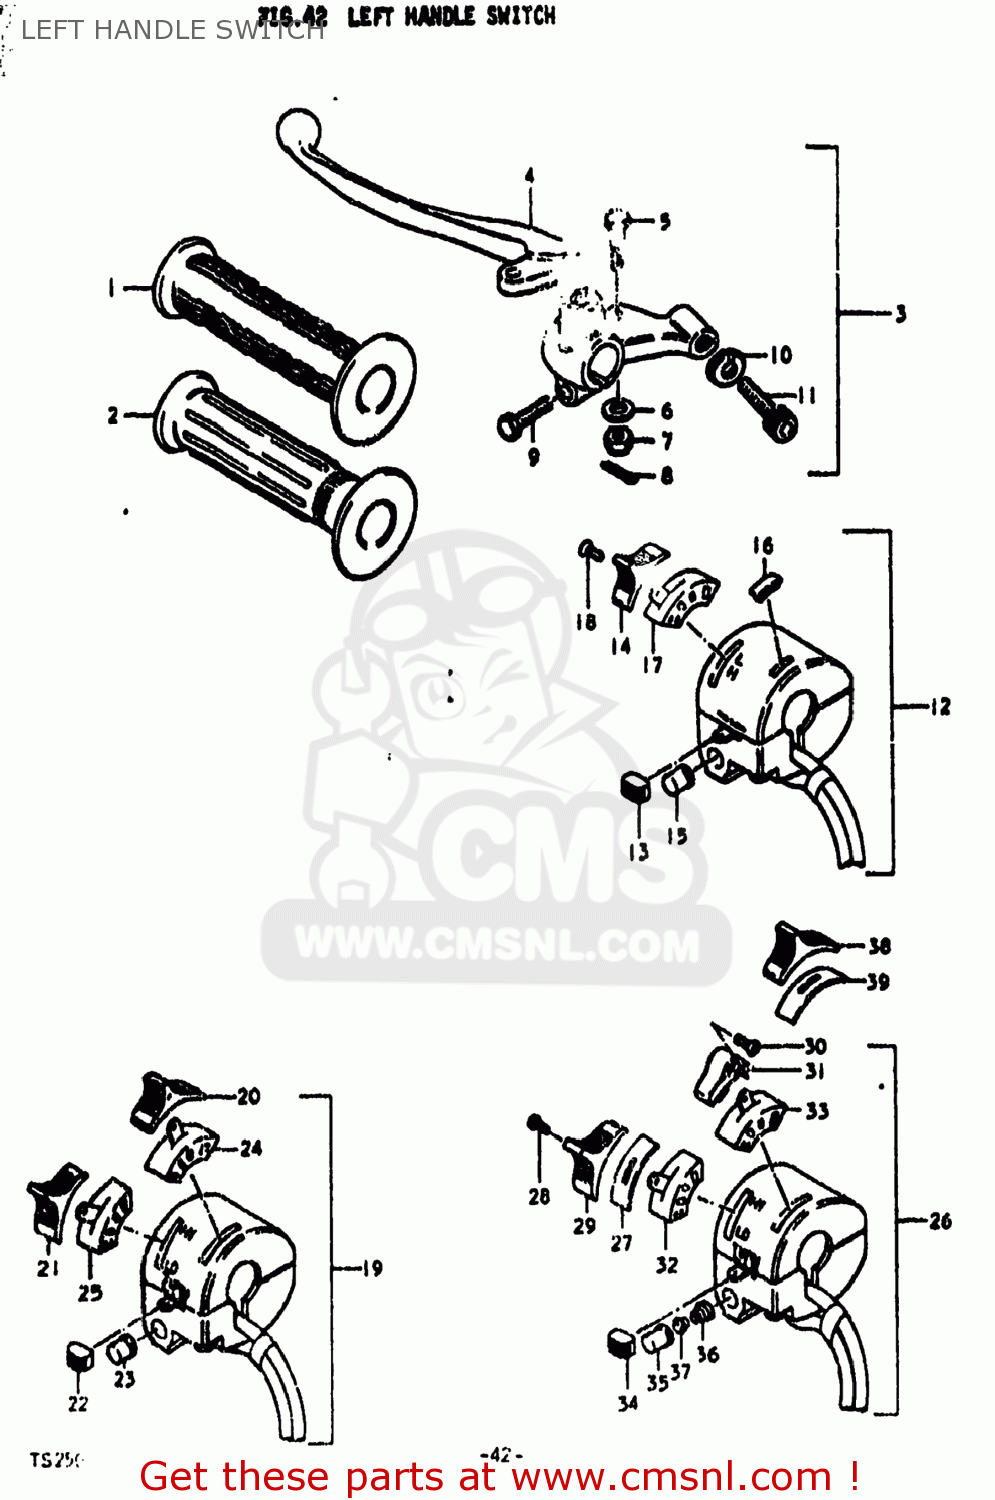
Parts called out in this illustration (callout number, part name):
1	GRIP
2	GRIP,L
3	LEVER ASSEMBLY
4	LEVER,CLUTCH
5	BOLT,LEVER
6	LOCK WASHER
7	NUT,LEVER FITTNG
8	COTTER PIN
9	BOLT
10	NUT,CABLE ADJUSTER
11	ADJUSTER,CABLE
12	SWITCH ASSEMBLY,HANDLE
13	KNOB,HANDLE SWITCH
14	KNOB,HANDLE SWITCH
15	BUTTON, HORN
17	DIMMER SWITCH BLOCK
18	SCREW
19	SWITCH ASSEMBLY,HANDLE
20	KNOB,HANDLE SWITCH
21	KNOB,HANDLE SWITCH,UPPER
22	KNOB,HANDLE SWITCH
23	BUTTON, HORN
25	SLIDING BLOCK, DIMMER SWITCH
26	SWITCH ASSEMBLY,HANDLE,LEFT
27	PLATE,DIMMER KNOB
28	SCREW, DIMMER
29	KNOB,HANDLE SWITCH,UPPER
30	SCREW
31	KNOB
32	SLIDING BLOCK, DIMMER SWITCH
34	KNOB,HANDLE SWITCH
35	BUTTON, HORN
36	SPRING,BUTTON
37	PLATE,HORN BUTTON
38	KNOB,HANDLE SWITCH
39	PLATE,LIGHTING KNOB
